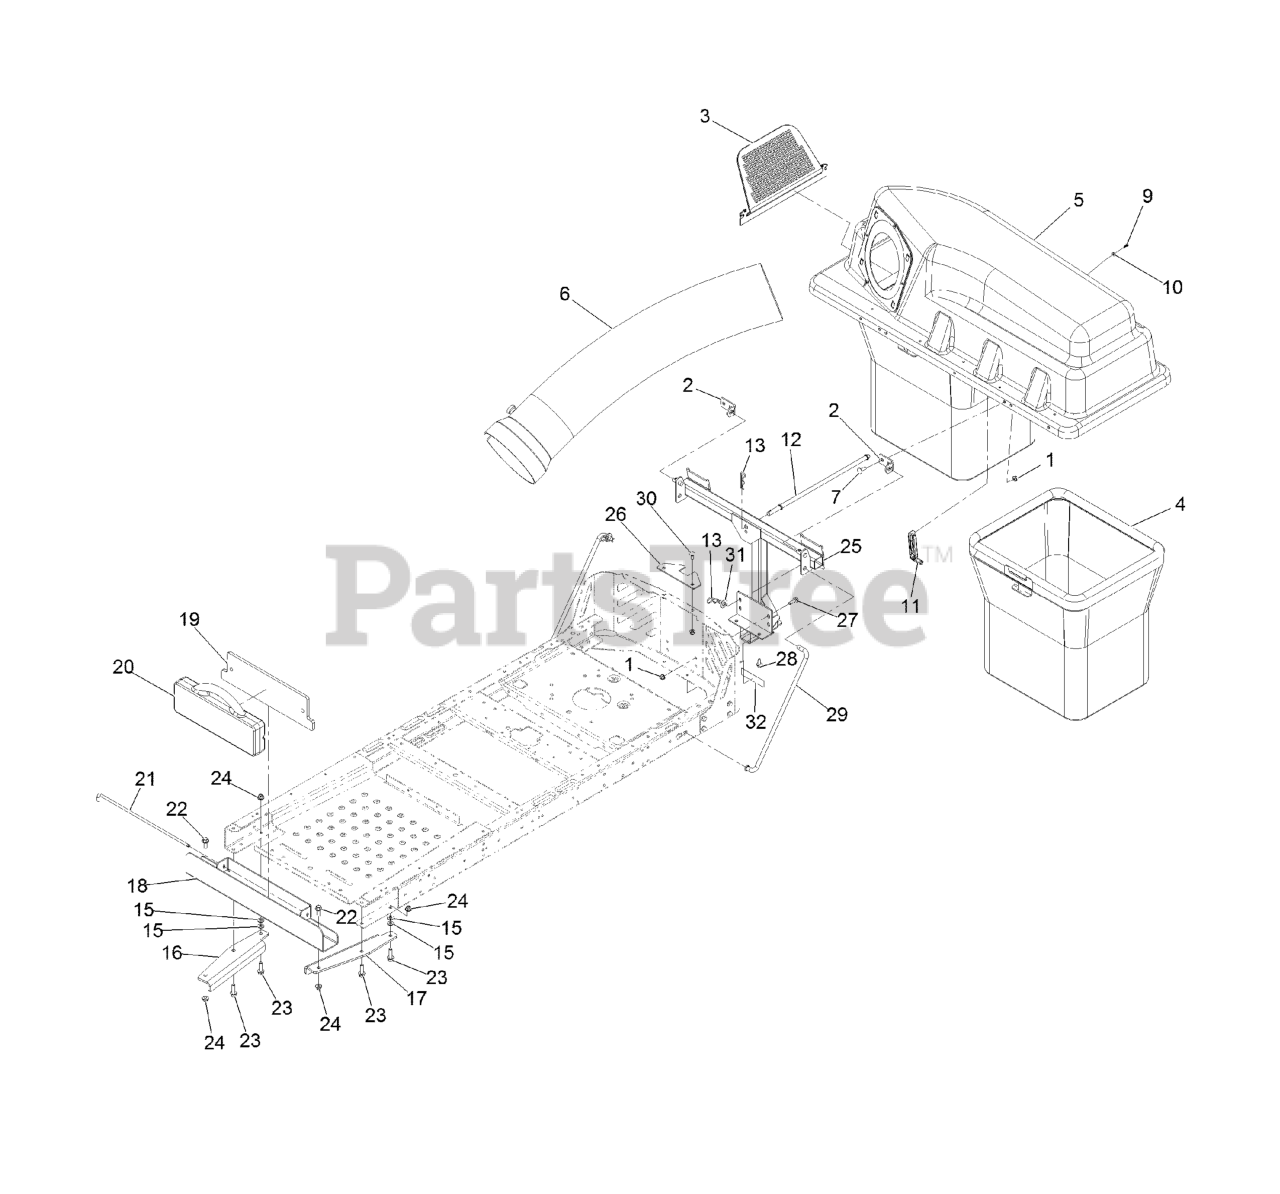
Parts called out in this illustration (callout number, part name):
1	NUT-HF, NI
2	BRACKET-PIVOT, HOPPER
3	SCREEN-BAGGER
4	BAG ASM
5	BAGGER TOP ASM
6	TUBE-BAGGER
7	BOLT-CARR
9	SCREW-PLASTIC, PTH
10	WASHER-FLAT
11	LATCH-RUBBER
12	ROD-HOOD, DOWN (HOLD)
13	PIN-HAIR
15	WASHER-FLAT
17	BRACKET-BAGGER WEIGHT, LH
18	CHANNEL-WEIGHT, BAGGER
20	WEIGHT-35 POUND
21	PIN-WEIGHT
22	SCREW-HHF 3/8-16 X 1
23	SCREW-HHF
24	NUT-HF, NI
25	PIVOT FRAME ASM
26	BRACKET-STABILIZER
27	SCREW-HHF
28	Screw-HWH 5/16-18 X 3/4 Tf
29	ROD-SUPPORT
30	BOLT-CARR
31	WASHER-FLAT
